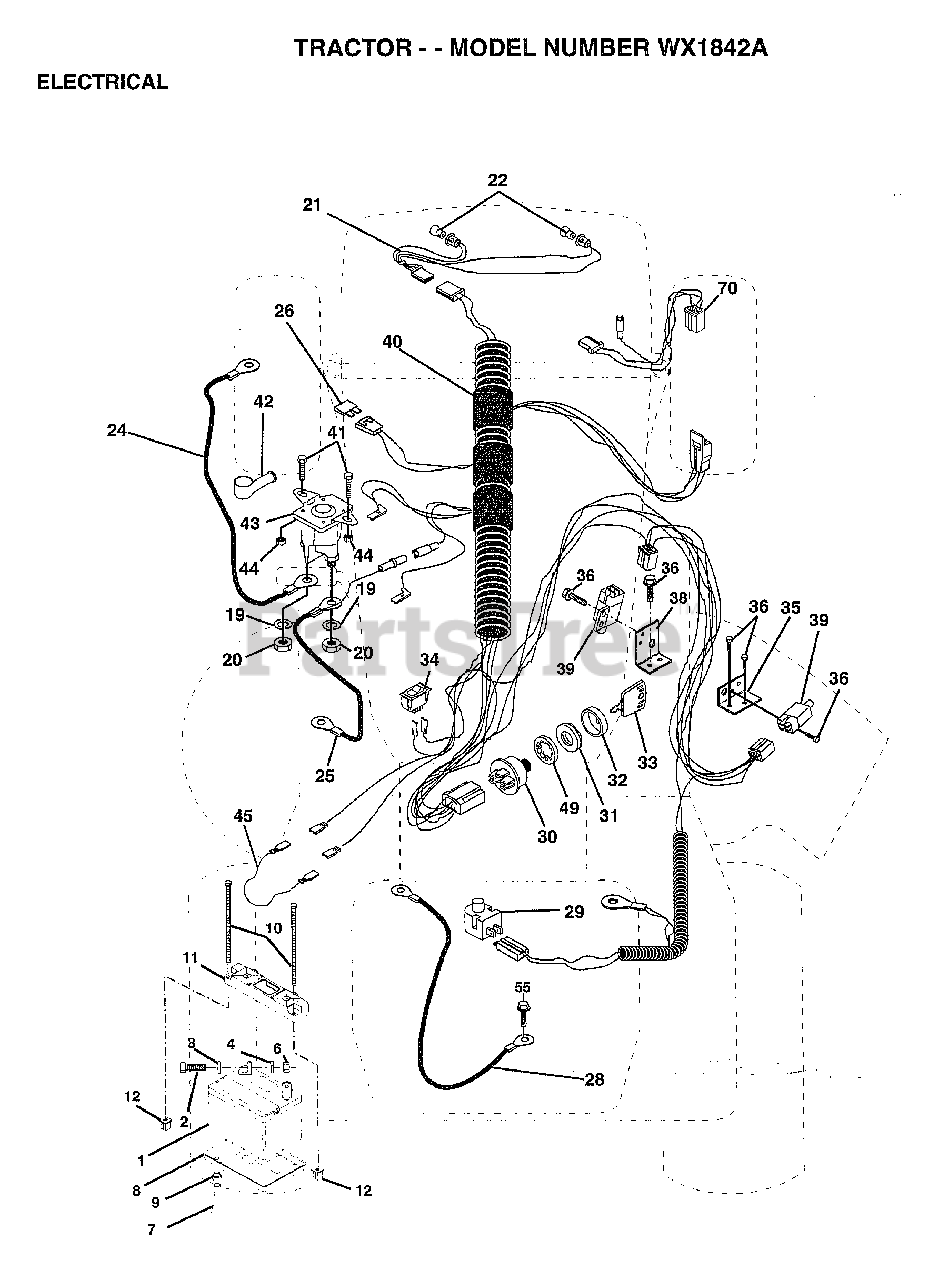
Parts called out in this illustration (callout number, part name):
2	BOLT LT
3	WASHER
4	LOCKWASHER
7	"DRAIN TU T, BATT"
8	"TRAY T, BATTERY"
9	HOSE CLAMP T
20	NUT
21	"HARNESS,LIGHT SOC"
22	HEADLAMP BULB
24	CABLE-BATTERY T
25	CABLE.6GA.22W/16W
26	FUSE HYT
28	CABLE.GRND.6GA.21
29	SWITCH SEAT
32	COVER KEY SWITCH
33	KEY MLD GEN DELTA
34	SWITCH LT
35	BRACKET LT
36	SCREW
38	BRACKET SWITCH IN
39	SWITCH INTERLOCKT
40	HARNESS.IGN.DASH.
41	BOLT HXHD FIN
44	NUT HXKEP 1/4X20
45	ADAPTER AMMETER
49	LOCKWASHER
55	SCREW LT
70	HARNESS ENG DUAL
